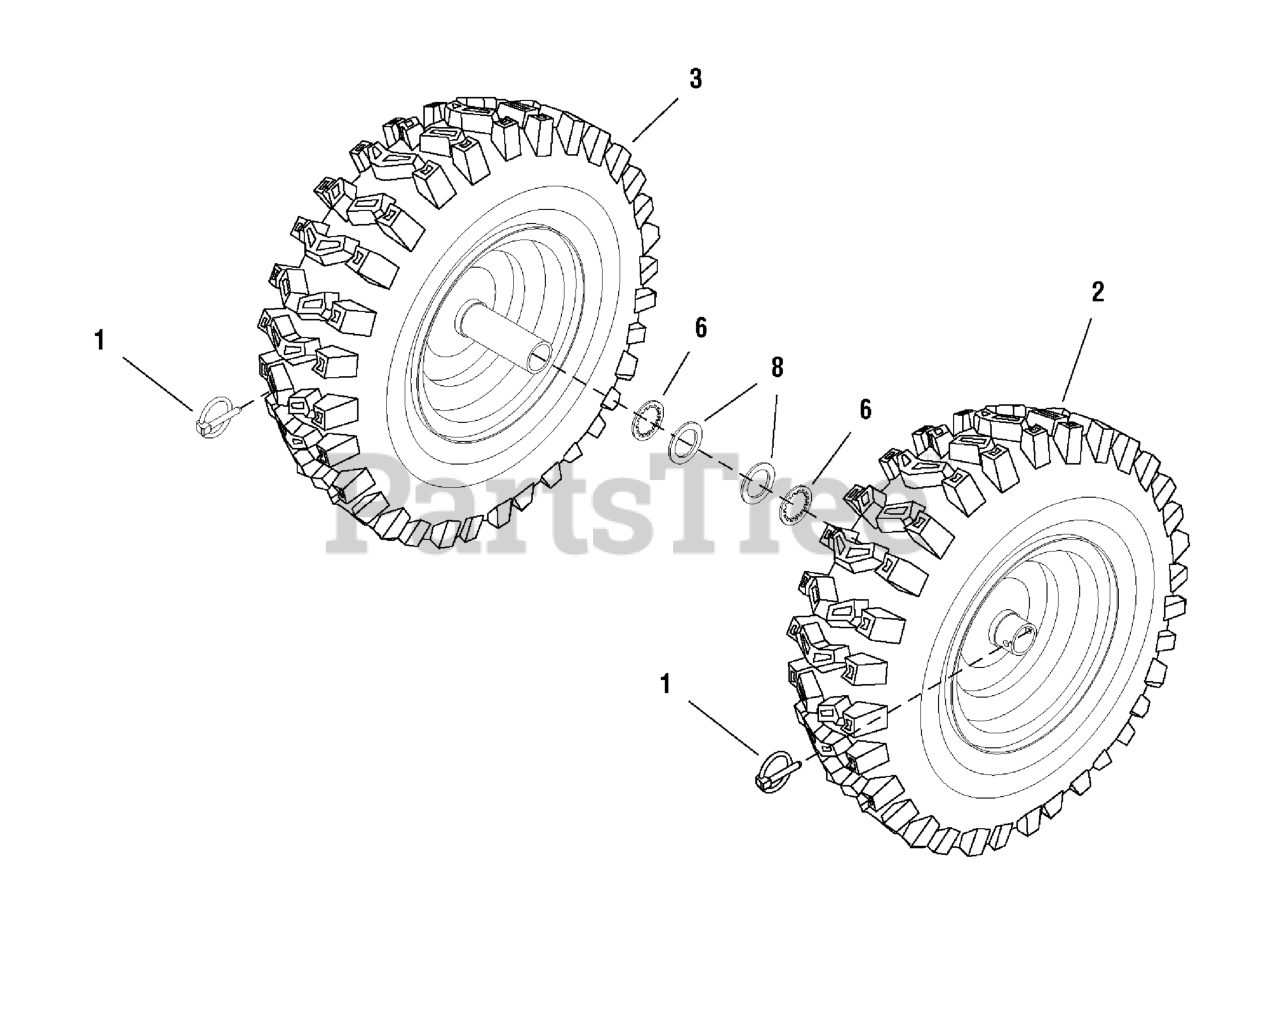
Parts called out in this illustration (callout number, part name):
1	PIN, Klik
2	WHEEL & TIRE ASSEMBLY, L.H. SNOW XTRAC 16 x 6.5-8
3	WHEEL & TIRE ASSEMBLY, R.H. SNOW XTRAC 16 x 6.5-8
6	RETAINING RING, Extertal, #75 0.750 Self Lock
8	WASHER, Flat .765 x 1.12 x .06 YZ
